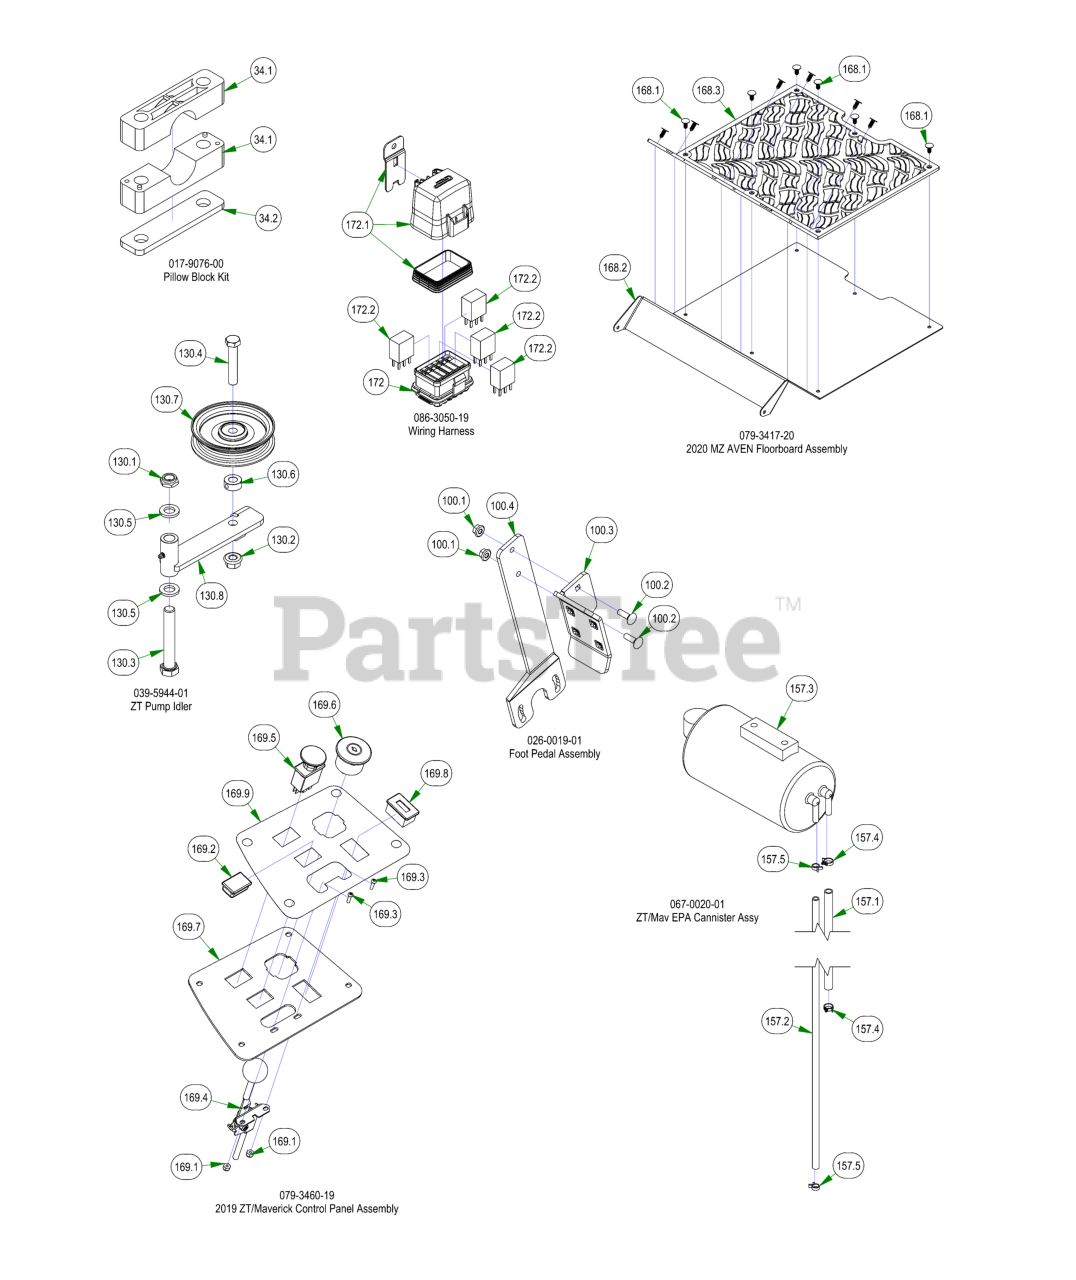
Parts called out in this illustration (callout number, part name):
34	Pillow Block Kit
34.1	Pillow Block MZ
34.2	Pillow Block Strap
100	Foot Pedal Assembly
100.1	5/16-18 NYLON INSERT FLANGE LOCKNUT ZINC
100.2	5/16-18 X 1 CARRIAGE BOLT (GR.8) ZINC
100.3	2017 MZ/ZT Shallow Foot Pedal
100.4	2017 MZ/ZT Deck Pedal Lever
130	ZT Pump Idler
130.1	5/8-11 NYLON INSERT JAM LOCKNUT ZINC
130.2	1/2-13 NYLON INSERT FLANGE LOCKNUT ZINC
130.3	5/8-11 X 4 HEX CAP SCREW (GR.8) ZINC YELLOW
130.4	1/2-13 X 2-3/4 HEX CAP SCREW (GR.5) ZINC
130.5	.635 ID X 1.120 OD X .140 THICK FLAT WASHER NYLON
130.6	1/2 SOLID SHAFT COLLAR (W/1 SET SCREW) ZINC
130.7	4 3/4" Idler Pulley
130.8	Pump Idler Bracket
157	ZT/Mav EPA Cannister Assy
157.1	1/4" Vinyl Tubing, 46" Long
157.2	3/16" Vinyl Tubing, 55" Long
157.3	Carbon Canister
157.4	3/16 Vinyl Clamp
157.5	3/16" Vinyl Hose Clamp
168	2020 MZ AVEN Floorboard Assembly
168.1	Ratchet Fastener
168.2	MZ/ZT 2017 Floorboard
168.3	2021 Maverick Floor Mat W/ Reaper Tread
169	2023 Control Panel Assembly
169.1	10-24 Nylon Insert Locknut Zinc Orange Nylon
169.2	Light Plug
169.3	10-24 X 5/8 BS Button Head Bolt
169.4	Throttle Lever Assembly
169.5	PTO Engager
169.6	Ignition Switch
169.7	2022 Maverick HD control panel
169.8	Tachometer
169.9	2023 MZ/Magnum/ZT/Maverick Control Panel Decal
172	Wiring Harness
172.1	Relay Block Cover Replacement Kit
